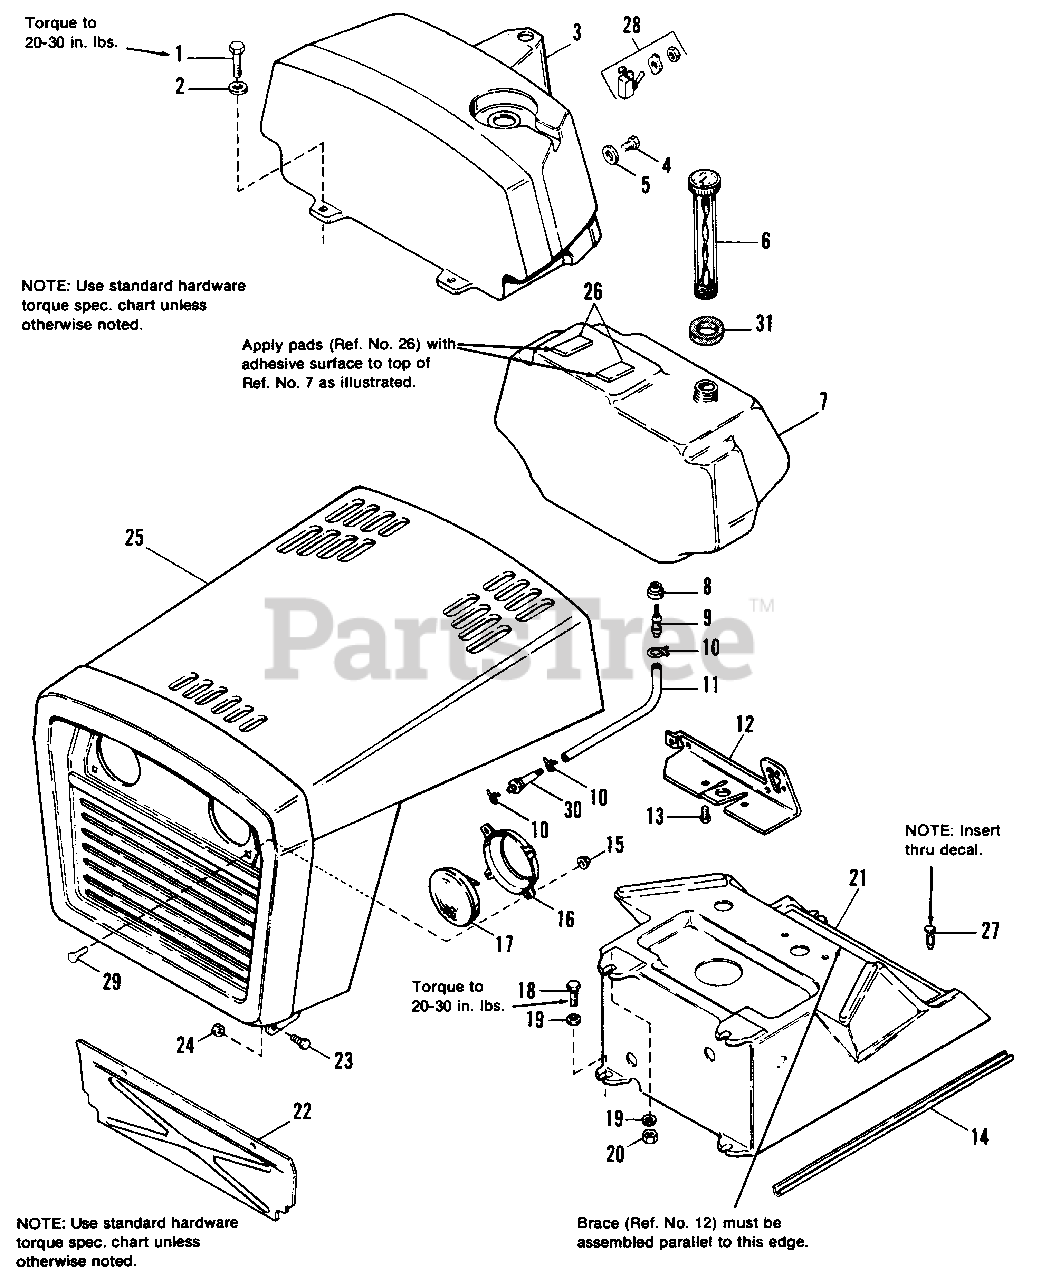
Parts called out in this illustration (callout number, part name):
1	CAPSCREW, Hex Hd., 1/4-20 x 1-1/4
2	WASHER, Plain, 1/4
3	DASH BOARD, Top
4	SCREW, #14 x 3/4
5	WASHER, Plain, 3/16
7	TANK ASSY., Fuel
10	CLAMP, Hose
12	BRACE, Dash
13	SCREW, Hex, Taptite, 1/4-20 x 1
14	EDGING, Lower Dash
15	LOCKNUT, Pal, #10-24
16	BRACKET, Support, Headlight
17	LAMP, Sealed Beam, G.E. #4411-1
18	SCREW, Hex, Taptite, 1/4-20 x 1
19	LOCKWASHER, Dished Type, 1/4
20	LOCKNUT, Hex, 1/4-20
21	DASH BOARD, Bottom
22	BAFFLE, Engine, Front (All models except 1691095 & 1691272)
23	CAPSCREW, Hex Hd., 3/8-16 x 7/8
24	LOCKNUT, Hex, 3/8-16
25	HOOD & GRILLE ASSY.
27	CLIP, Canoe
28	SWITCH, Toggle, Lights
29	BOLT, Carriage, #10-24 x 1/2
30	FILTER, Fuel
31	FOAM, Washer
